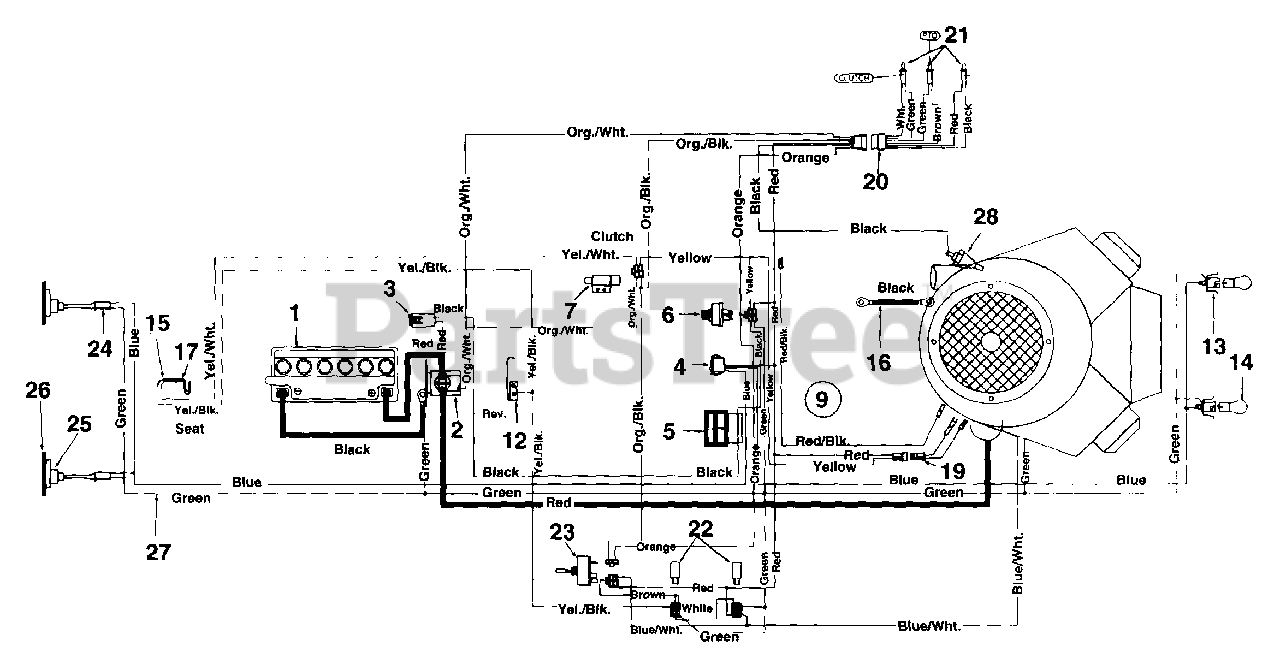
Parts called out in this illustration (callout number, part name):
1	Battery
2	Solenoid
3	Fuse 20 Amps
4	Light Switch
5	Ammeter
6	Ignition Switch
7	Safety Switch
9	Wire Harness
12	Safety Switch (Reverse)
13	Socket
14	Bulb (Headlight)
15	Safety Switch (Seat)
16	Ground Wire 7.5" Lg.
17	Safety Switch (Seat)
19	Harness Adapter
20	Monitor Harness
21	Monitor Bulb
22	Relay
23	Safety Switch (PTO)
24	Taillight Harness
25	Taillight
26	Taillight Bulb
27	Taillight Adaptor Harness
28	Oil Pressure Switch
